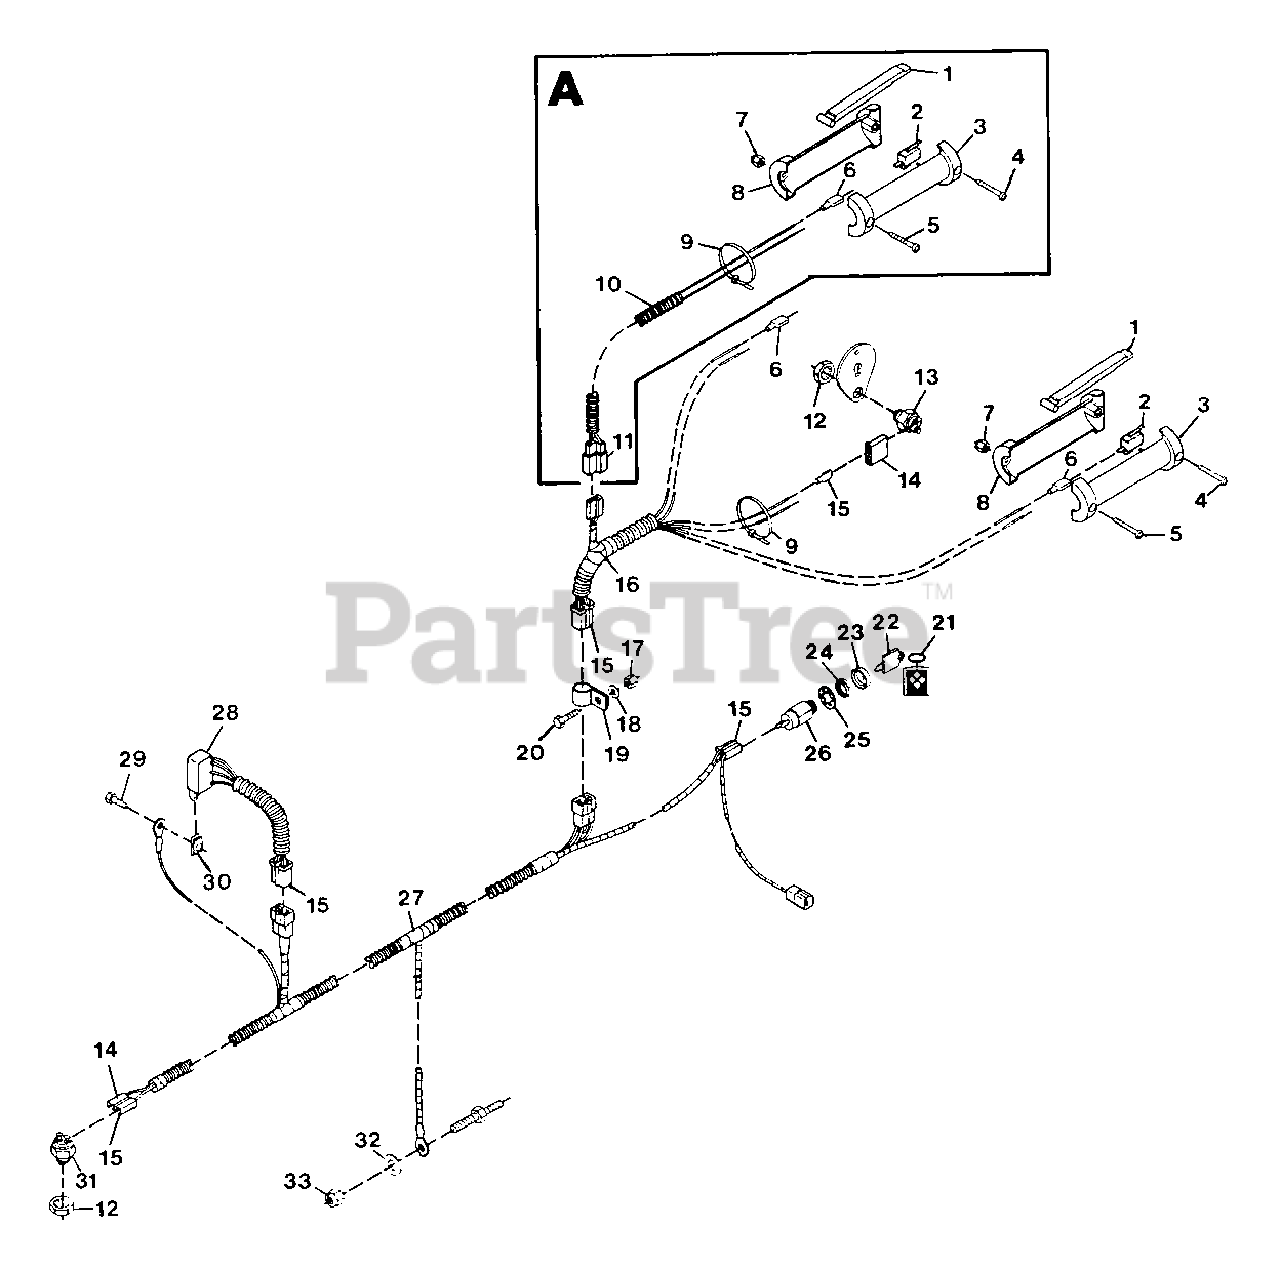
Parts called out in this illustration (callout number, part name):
1	Lever
2	Switch
3	Handle, L.H.
4	Screw, Mach. 10-24x.75 PHD
5	Screw, Mach. 10-24x1.50 PHDCR
6	Terminal, Female
7	Nut, Lock 10-24
8	Handle, R.H.
9	Tie Wrap, Black
10	Harness, Steering Brake
11	Connector
12	Nut, Stamped 9/16-18
13	Switch, Neutral Start Gold
14	Connector, 2-Wire Switch
15	Terminal
16	Harness, Wiring Handlebar
17	Nut, Lock 1/4-20
18	Washer, Flat .281x.625x.065
19	Clamp, Nylon
20	Bolt, Hex 1/4-20x.75
21	Chain, Key
22	Key, Ignition Switch
23	Boot, for 9/16 Switch
24	Nut, 5/8-32 for Switch
25	Washer, Lock 5/8 Int. Tooth
26	Switch
27	Harness, Wiring
27	New Harness with screw in eyelets
28	Module, Interlock Recoil
29	Bolt, Hex 1/4-20x.625
30	Nut, Speed 1/4-20
31	Switch, Interlock Silver
32	Washer, Flat .469x.938x.065
33	Nut, Lock 3/8-16
